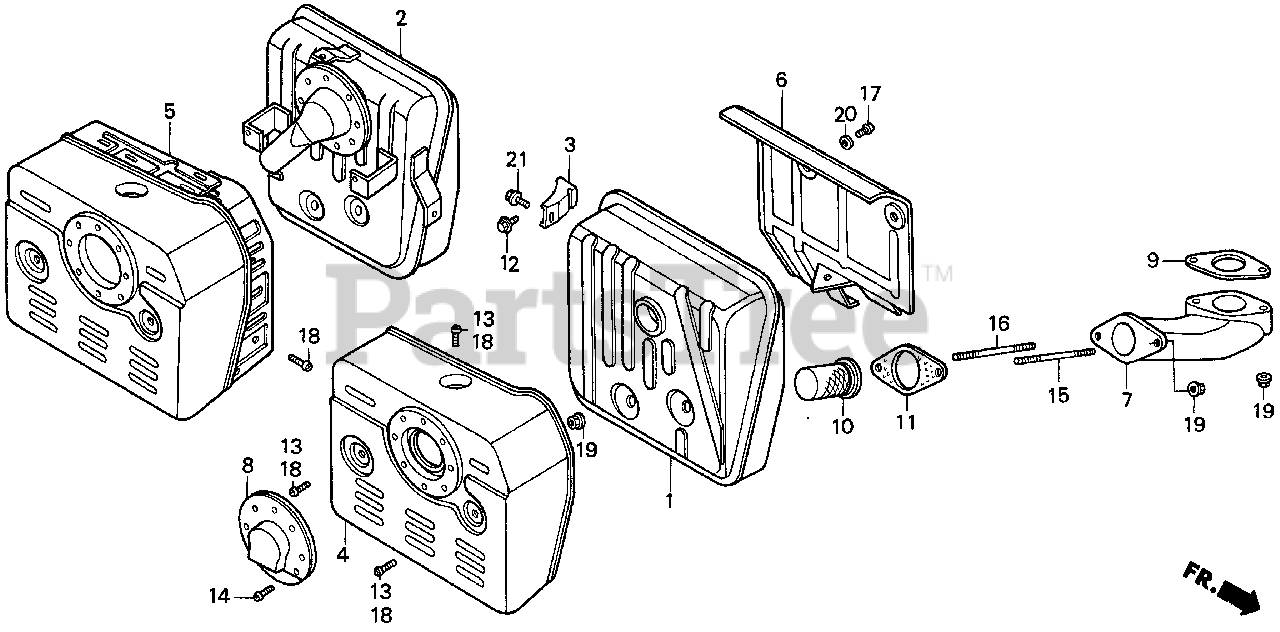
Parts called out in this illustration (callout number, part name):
2	MUFFLER
3	STAY, MUFFLER
5	PROTECTOR, MUFFLER
6	SEPARATOR, MUFFLER
7	PIPE, EX.
9	GASKET, EX. PIPE
9	GASKET, EX. PIPE (WACKER)
11	GASKET, EX. PIPE
12	BOLT, FLANGE (8X16)
15	BOLT, STUD (8X60)
16	BOLT, STUD (8X70)
17	SCREW, PAN (6X6)
18	SCREW, TAPPING (5X8)
19	NUT, FLANGE (8MM)
20	WASHER, PLAIN (6MM)
21	BOLT, FLANGE (8X14)
